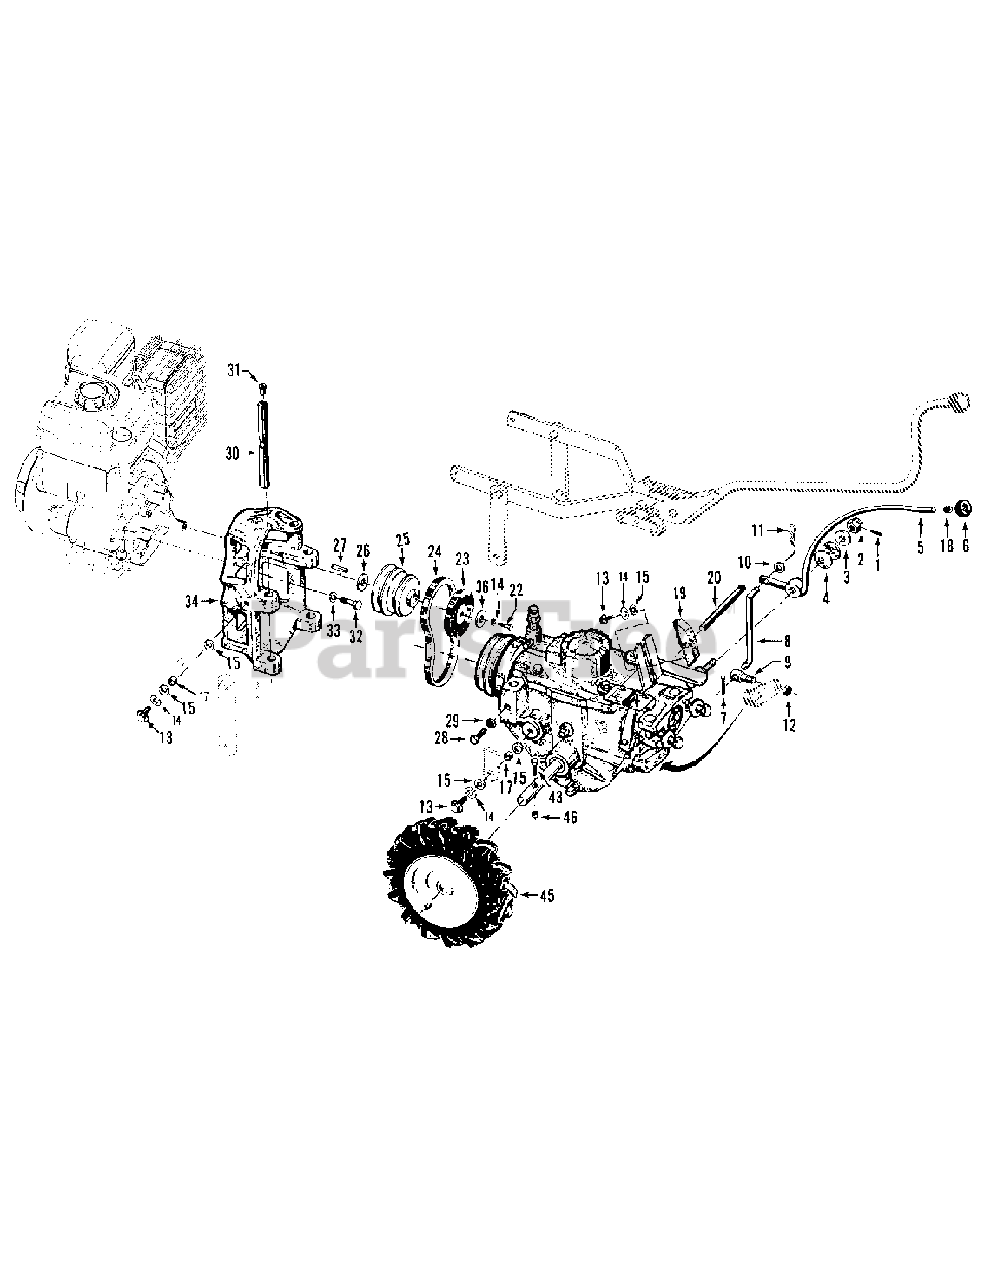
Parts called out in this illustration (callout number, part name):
1	Pin-spring, 1/8"
2	Nut-castle (slotted), 1/2" - 20
3	Washer-shoulder, 1/2"
4	Washer-disc spring
5	Lever-wheel speed shift
6	Knob-wheel speed shift lever
7	Pin-cotter, 3/32" x 1"
8	Connecting rod, wheel speed shift lever (Incl Ref.7 & Ref. 9
9	Swivel-connecting rod
10	Washer-flat, 5/16", SAE
11	Pin-hair cotter
12	Locknut-hex hd., 5/16"-18
13	Bolt-flanged hex hd, 3/8-16, x 1"
14	Lockwasher-spring lock, 3/8"
15	Washer-flat, 3/8", SAE
17	Bushing-spacer, 19/64" (300"lg)
18	Ring-retaining (tolerance ring)
19	Block- belt adjustment, 3-7/8"
20	Rod- belt adjust., 7" with measuring gauge
21	Decal- engine stabilization
22	Bolt-hex hd., 3/8-24 x 1-1/2"
23	Disc-reverse
24	Belt-forward drive (no substitute due to extra strength required)
25	Pulley-engine power take off
26	Shim-engine pulley, 1/16"
26	Shim-as above, 1/32"
27	Key-engine pulley, 3 /16" sq. x 2-1/2"
28	Bolt-hexhd., 5/16-18 x 1", Grade 5
29	Nut, 5/16-18 hex,
30	Bar-engine mounting
31	Plug-thread protector, red plastic
32	Bolt-hex hd., 5/16-24 x 1-1/8"
33	Lockwasher-spring lock, 5/16"
34	Mount- engine to tiller
36	Washer, flat, .406 x 1.0 x .105
36	Decal-hot surface warning
43	Screw, Hex, 1/4-20 x 1-1/2" J
45	Wheel & Tire Assy - 16 x 4:6 x 8" tubeless tire w\valve stem, on one-piece steel rim. (For correct traction and directional control, Bar Tread Tires should be mounted on the closed end of the "V" in the tire tread on top of the tire faces forward
46	Nut, Hex Flange,1/4-20
